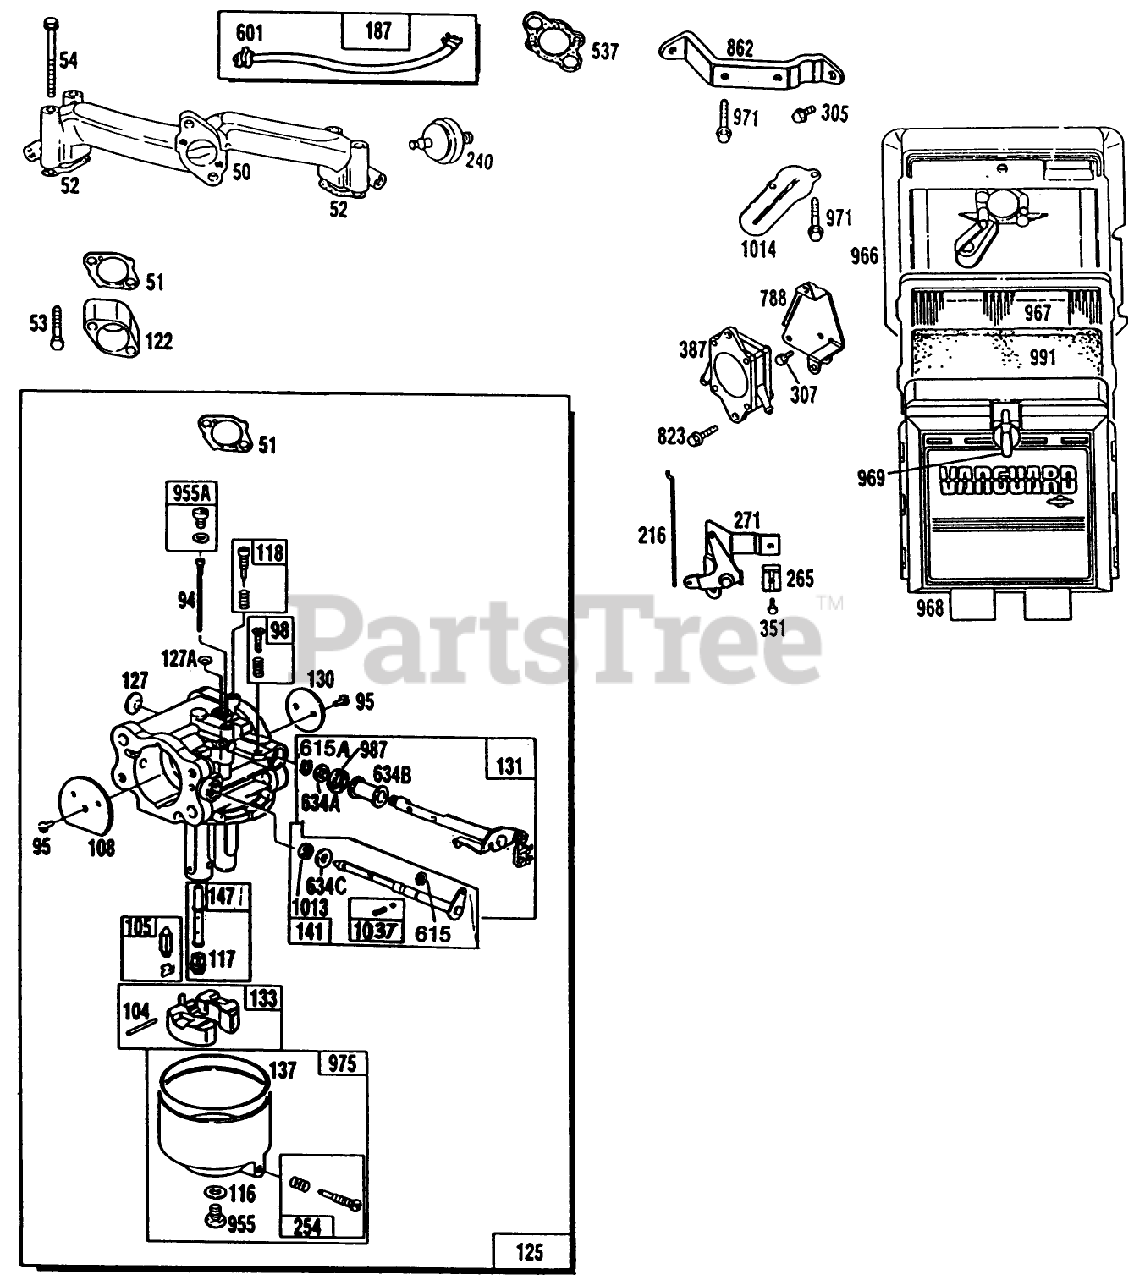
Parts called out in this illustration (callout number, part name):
50	BRIGGS-805409
51	BRIGGS-805149
52	BRIGGS 805023
53	BRIGGS-805360
54	BRIGGS-805006
94	BRIGGS-805565
95	BRIGGS-805561
98	BRIGGS-807705
104	BRIGGS 805586
105	BRIGGS-807706
108	BRIGGS-805562
116	BRIGGS-805058
117	BRIGGS-805198
118	BRIGGS-807707
122	BRIGGS-805329
125	BRIGGS-807639
127	BRIGGS 805570
127A	BRIGGS 805571
131	BRIGGS-807709
133	BRIGGS-807710
137	Gasket (Sold in Kit Only)
141	BRIGGS-807711
187	BRIGGS 296004
216	BRIGGS-805439
254	BRIGGS-807713
265	BRIGGS 805170
305	BRIGGS 805406
307	BRIGGS-78-4310
351	BRIGGS 805169
537	BRIGGS-805003
615	BRIGGS 805578
615A	BRIGGS 805577
634A	BRIGGS 805576
634B	BRIGGS-805574
634C	BRIGGS 805580
788	BRIGGS-807685
823	BRIGGS 805317
862	BRIGGS-807576
955	BRIGGS 805592
955A	BRIGGS-807714
969	BRIGGS-807565
971	BRIGGS 805405
975	BRIGGS-807715
987	BRIGGS 805575
991	BRIGGS-805267
1013	BRIGGS 805581
1037	BRIGGS 807717
